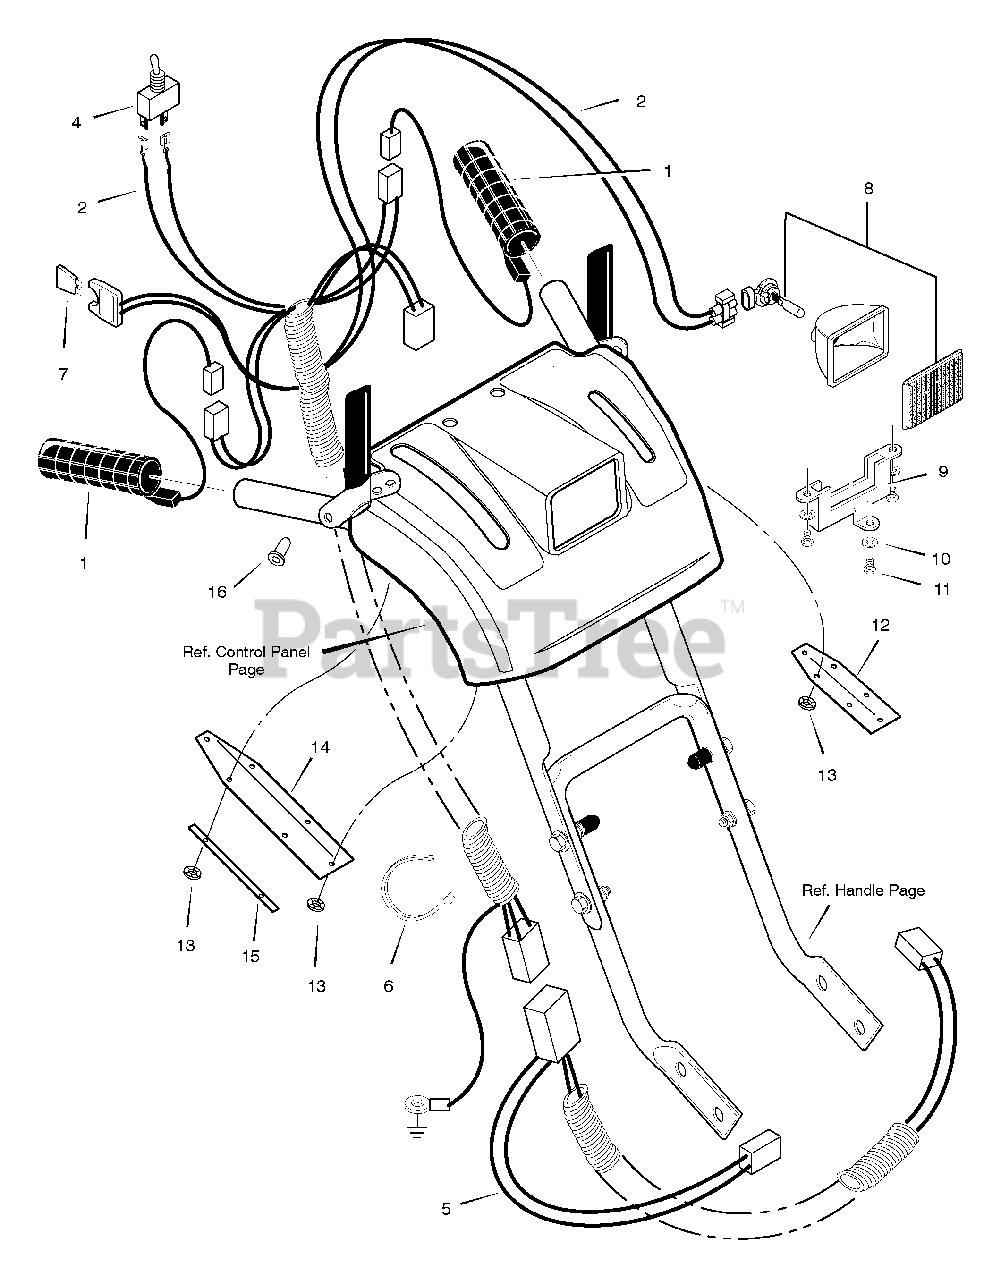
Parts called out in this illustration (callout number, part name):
1	GRIP, HEATED
2	WIRE HARNESS, UPPER
4	SWITCH, HEATED GRIP
5	WIRE HARNESS, LOWER
6	TIE, CABLE
7	FUSE, 7.5 AMP AUTOMOTIVE
8	HEADLIGHT ASSEMBLY *
9	BRACKET
10	WASHER, FLAT
11	SCREW #8 X .50
13	NUT, PUSH
16	RIVET, 0.125 x 0.23
